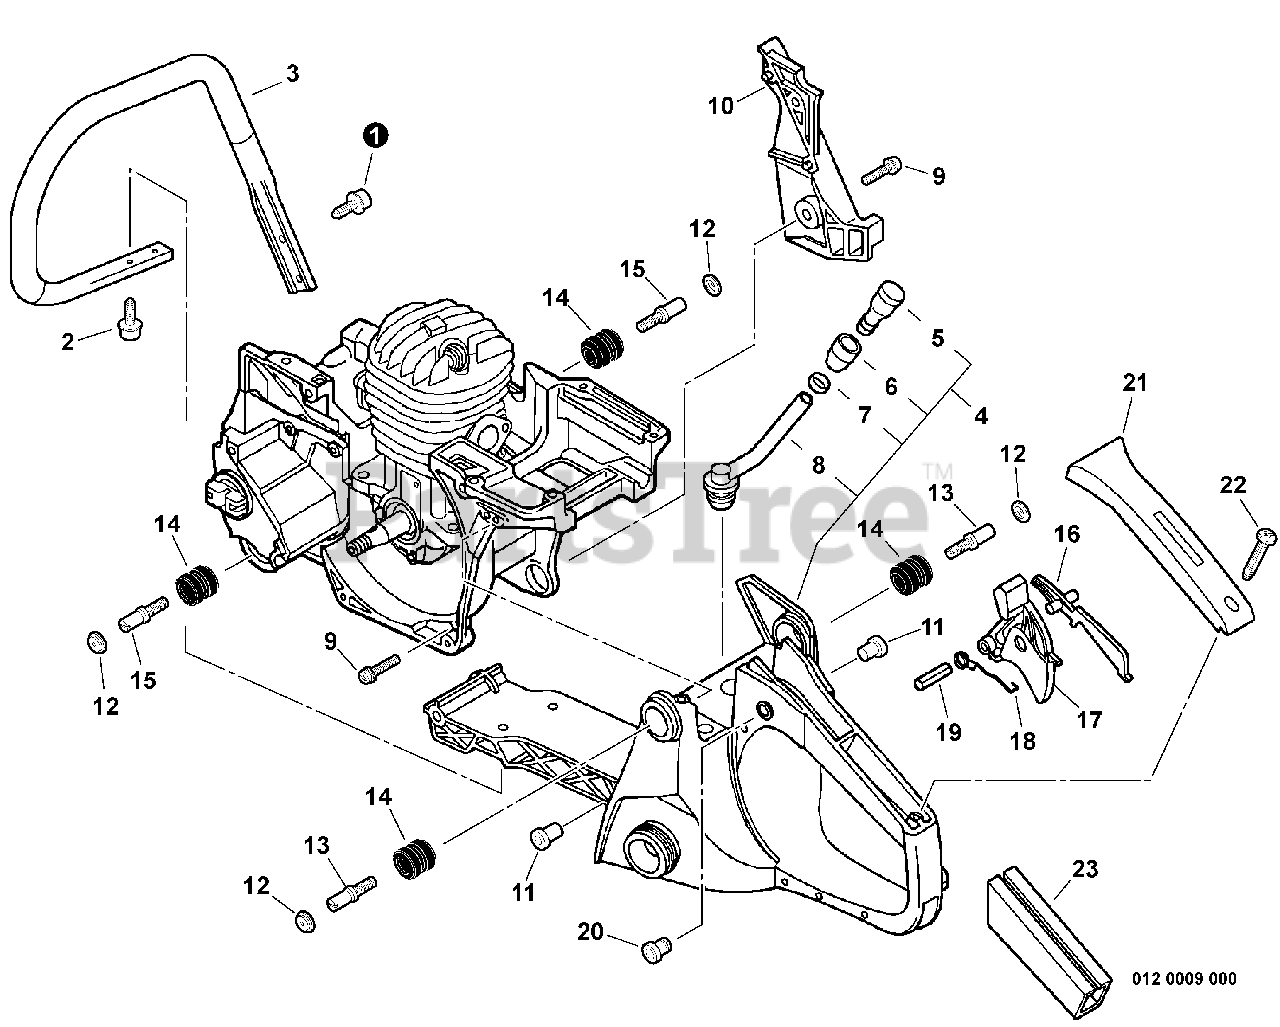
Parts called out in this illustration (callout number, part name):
1	SCREW TAPPING 5×20
2	SCREW TAPPING 5×16
3	HANDLE, FRONT
4	HANDLE ASSY, REAR
5	VENT ASSY
6	HOLDER, VENT
7	CLIP Ø6.5 MM
8	VENT ASSY
9	SCREW 5×16
11	CUSHION 5
12	CAP, CUSHION
14	CUSHION 5
16	LOCKOUT, THROTTLE
17	TRIGGER, THROTTLE
18	SPRING, TORSION
19	PIN, SPRING 4×30
21	COVER, HANDLE
22	SCREW 4×14
23	GRIP, HANDLE
